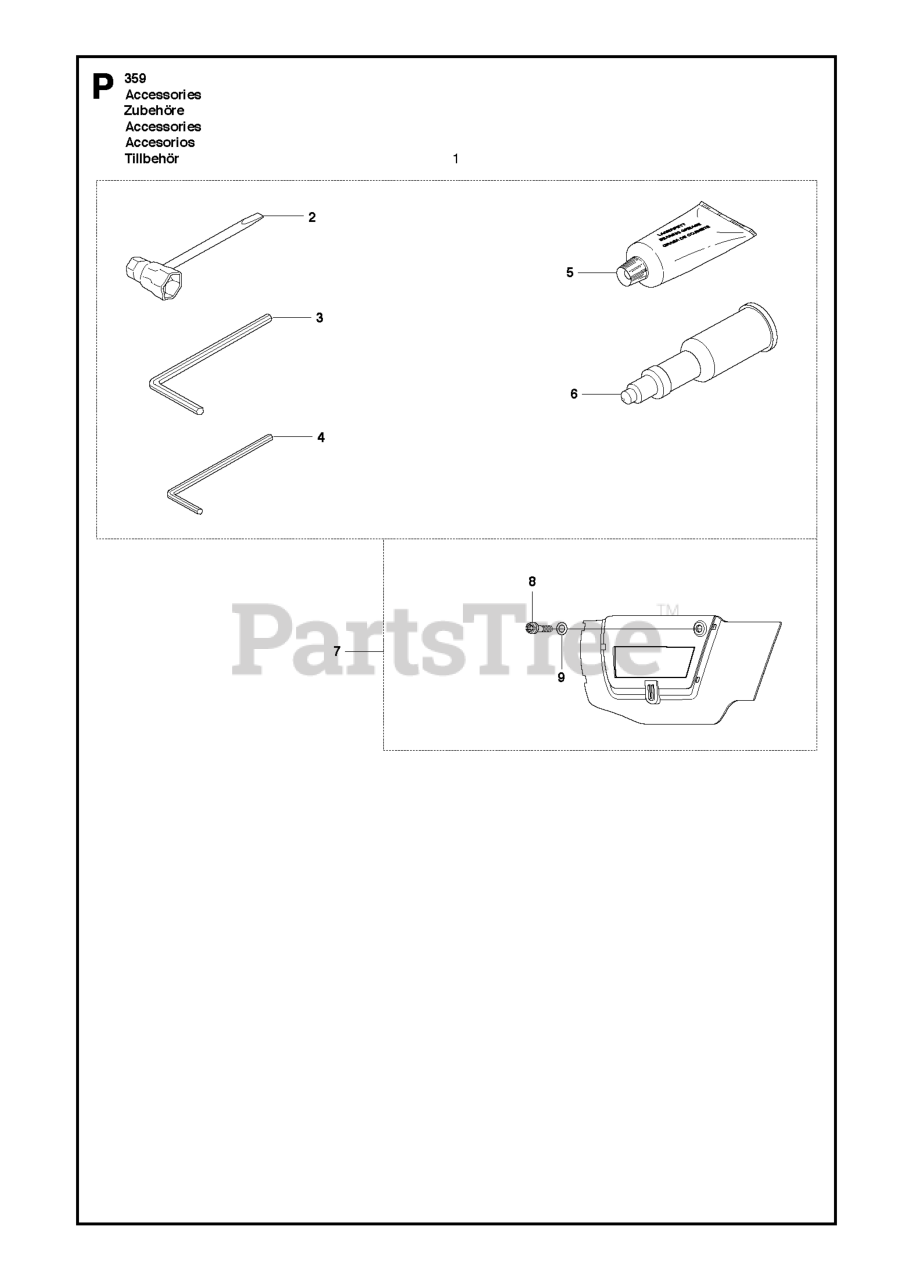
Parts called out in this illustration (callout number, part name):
1	TOOL KIT
2	COMBI TOOL
5	GREASE
6	Grease Gun
7	PROTECTOR
